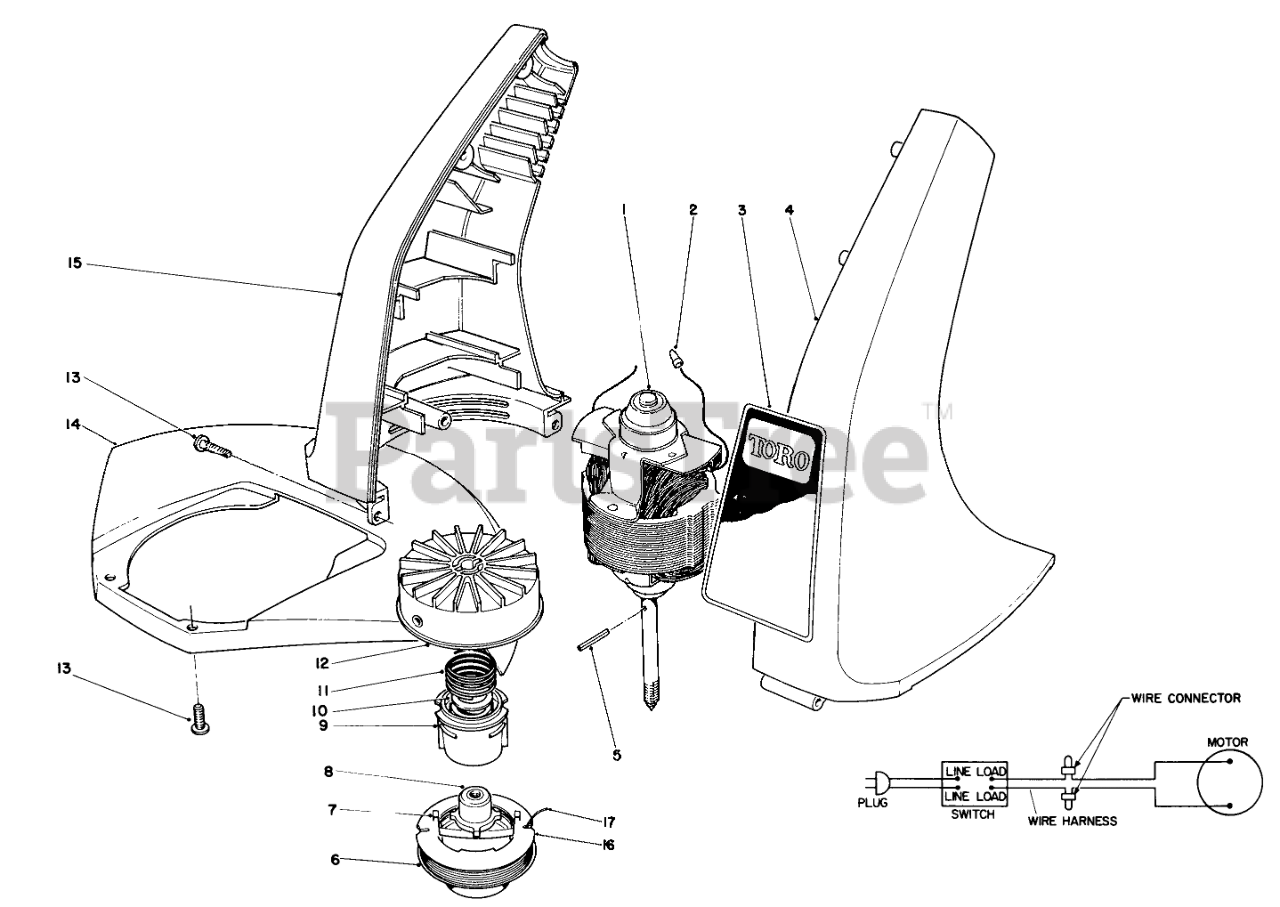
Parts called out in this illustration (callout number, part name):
1	Motor
2	CONNECTOR WIRE JOINT
3	DECAL, 12" TRIMMER
4	LH HOUSING, 12" TRIMMER
5	COIL PIN
6	Cutting Line (50 .065" Dia.)
7	SADDLE-SPOOL CAP
8	DRIVER
9	SPOOL CORE
10	WASHER-FLAT
11	SPRING COMPRESSION
12	DRUM W/EYELET
13	Screw
14	Shield (Incl. Ref. #18 & 19)
15	RH HOUSING, 12" TRIMMER
16	SPOOL CAP
17	LINE-FILIMENT
18	Rivet
19	Blade-Knife
